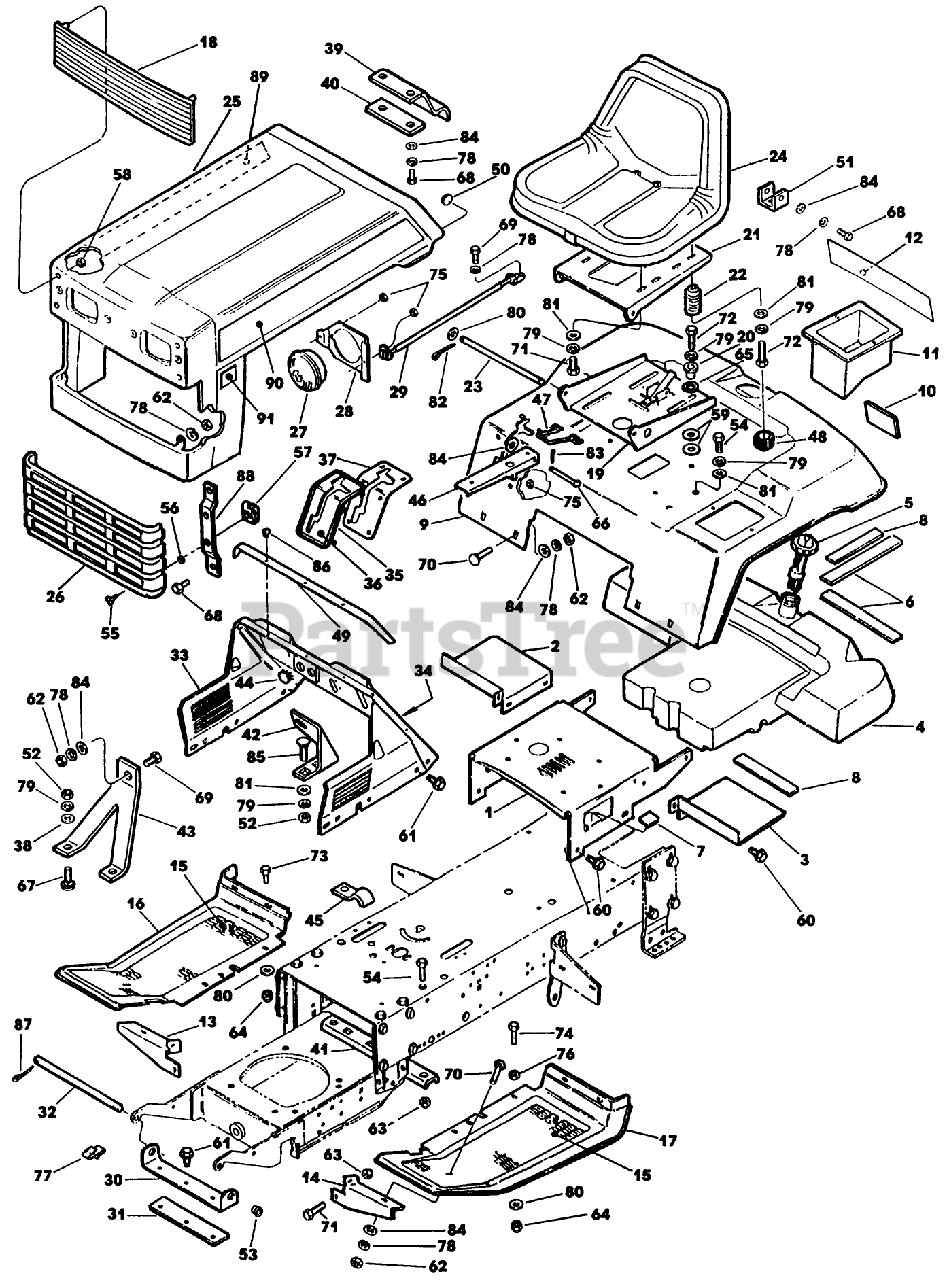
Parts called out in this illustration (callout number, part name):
4	TANK - FUEL
5	GUAGE ASSEMBLY-FUE
8	PAD - FUEL TANK
9	Fender Seat Support Ass-y.
10	REFLECTOR
16	FOOTREST - RH *G
19	SEAT SUPPORT AY
21	PIVOT AY - SEAT *B
23	PIN
24	SEAT
25	HOOD&GRILLE (UPS) *G
26	INSERT - GRILLE
32	ROD - HOOD PIVOT
43	BRACKET-SUPPORT
46	LATCH - SEAT PAN *B
48	CAP-PROTECTOR
52	NUT SS
53	BEARING-NYLINER
55	FASTENER-1/4 TURN
59	WASHER-PLASTIC
62	NUT
63	NUT
64	NUT-LOCKING
66	PIN
67	BOLT - CARRIAGE
68	SCREW-HH
69	SCREW
71	SCREW - HEX
72	SCREW
76	NUT
77	CLIP-RETAINER, WIRE
80	WASHER
90	DECAL - HOOD LH
